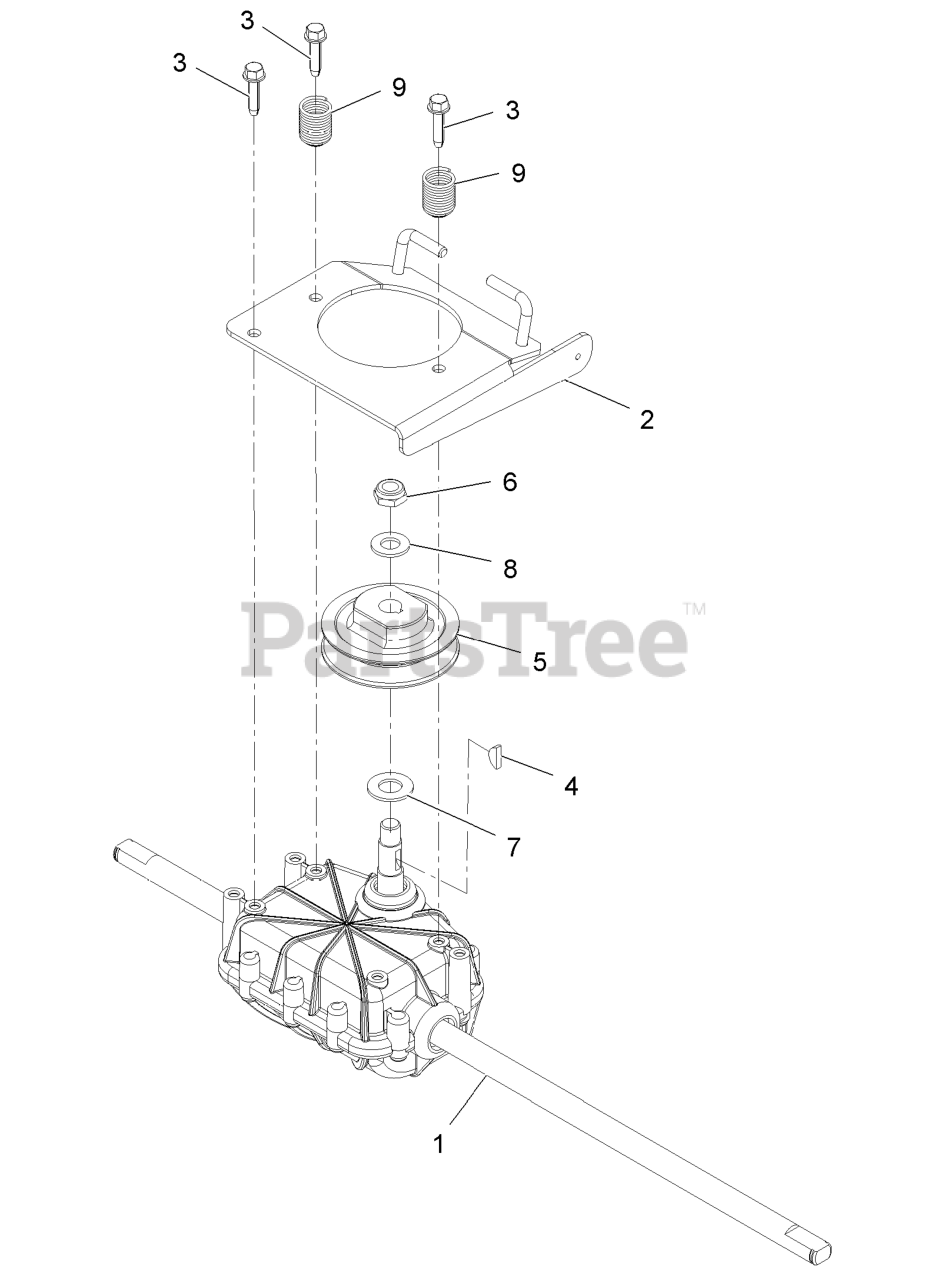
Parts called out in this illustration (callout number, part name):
2	TRANSMISSION PLATE ASM
3	SCREW-SPECIAL
4	KEY-WOODRUFF
6	NUT-HEX
7	WASHER-THRUST
8	WASHER-FLAT
9	SPRING,COMPRESSION
